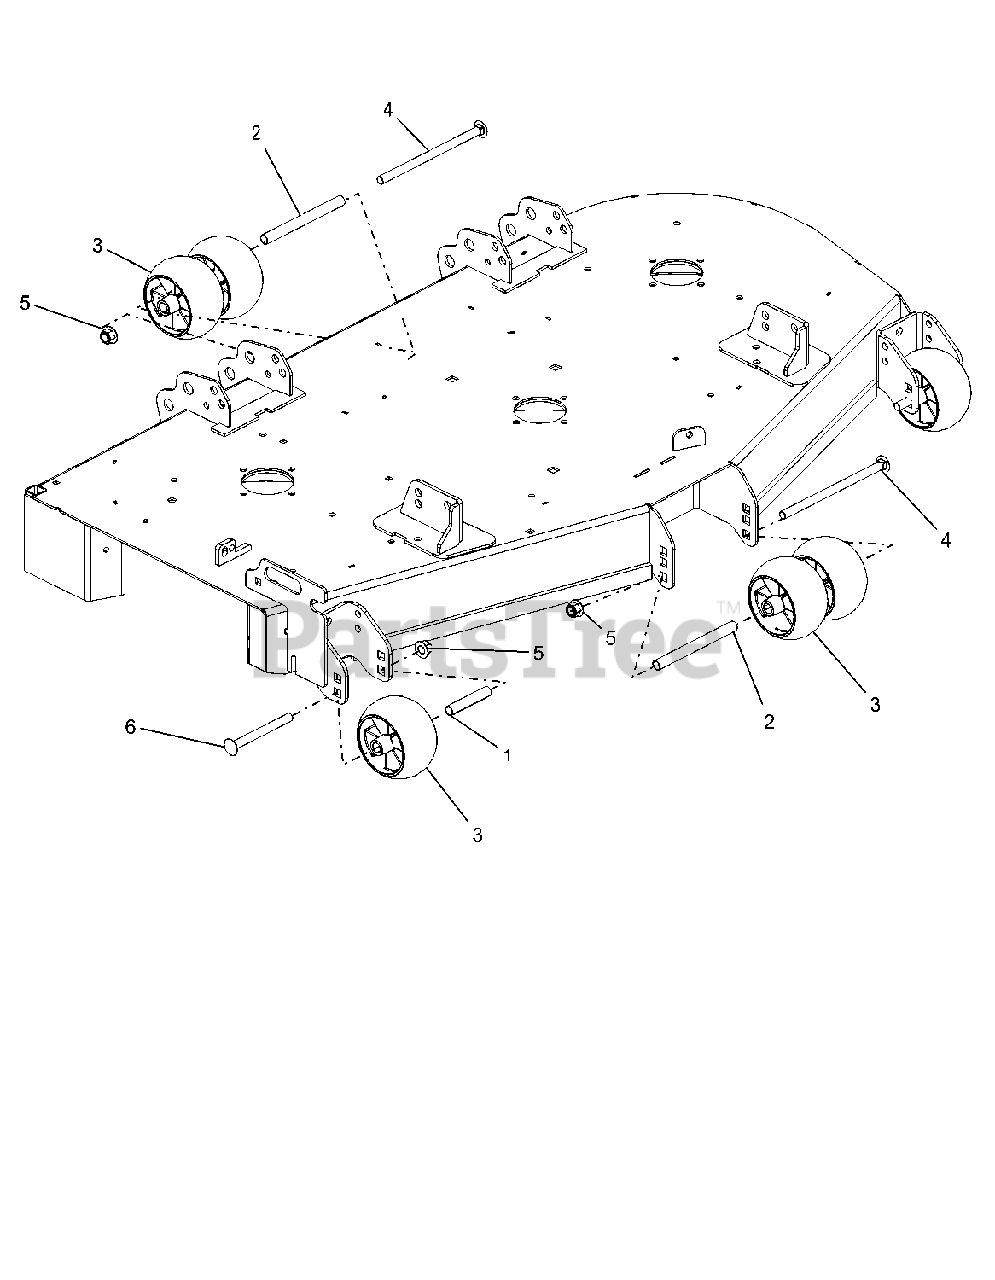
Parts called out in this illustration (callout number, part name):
1	SPACER, .510X.625X3.35
2	SPACER, .510 X .625 X 6.50
3	ANTI-SCALP WHEEL - 5X3 CTR
4	BLT-RDHDSQNK .50-13X8.50 Y
5	NUT-LK-NYL-FLG .50-13 YWZC
6	BLT-RDHDSQNK .50-13X5.00 G5 YWZC
